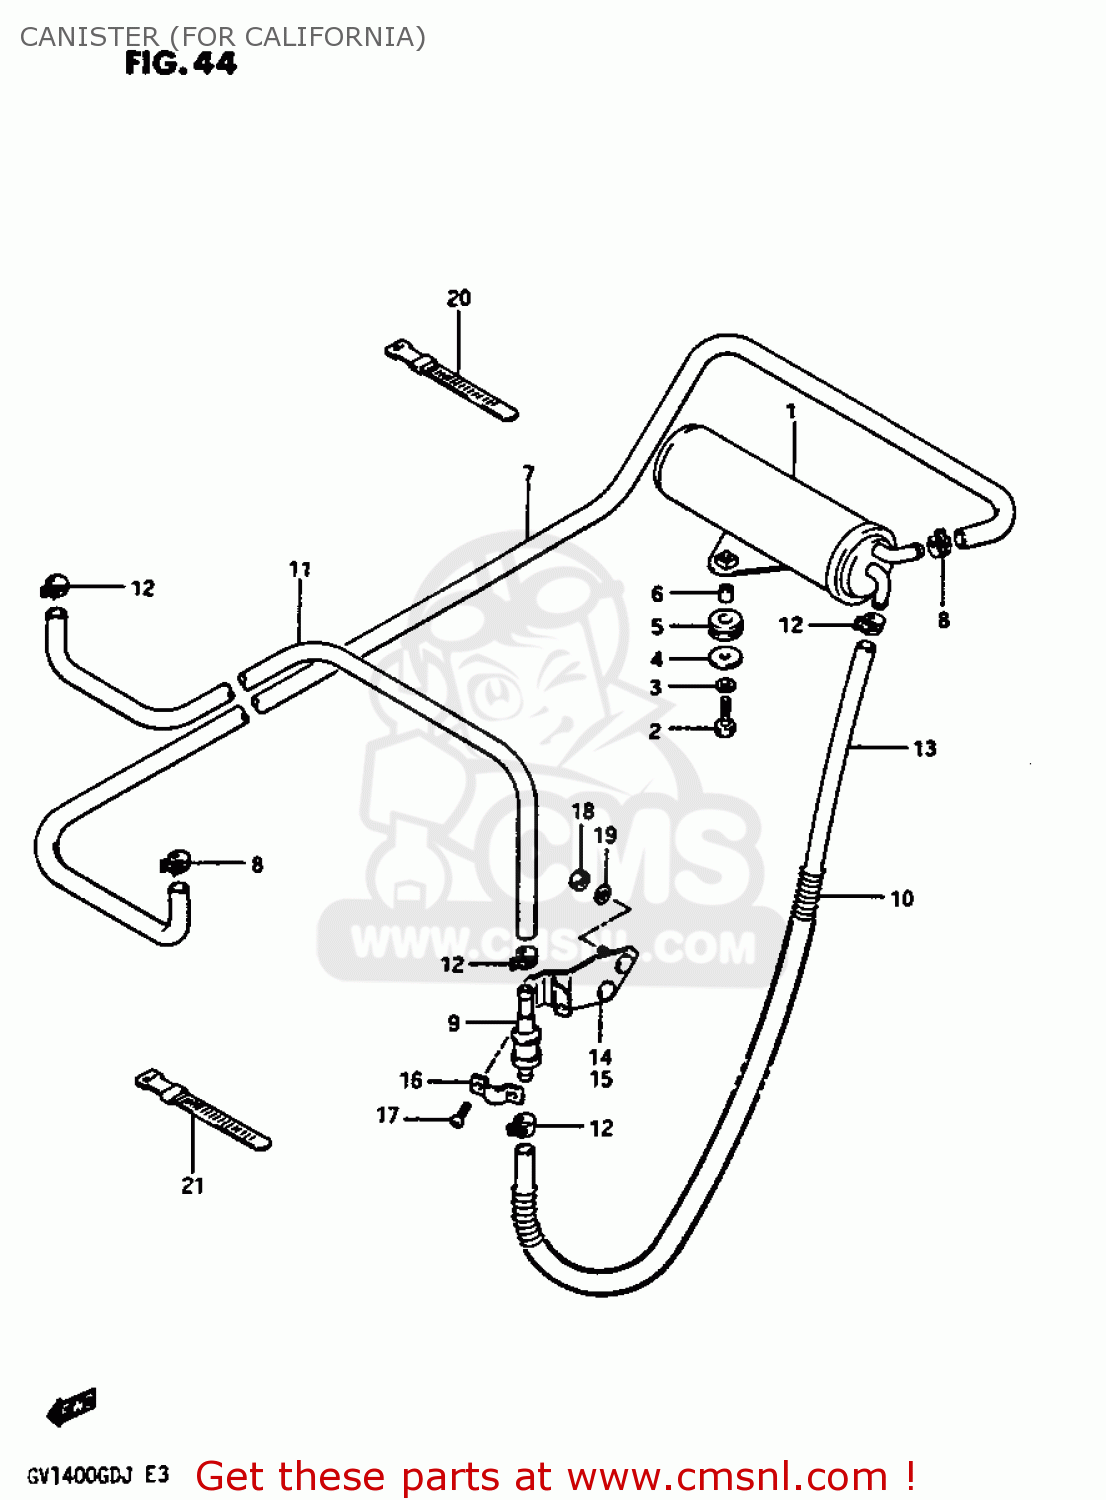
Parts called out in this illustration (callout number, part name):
1	(CA) CANISTER ASSEMBLY,CHARCOAL
2	BOLT
3	WASHER,LOCK
4	WASHER (6.5X18X1.6)
5	CUSHION
6	SPACER(6.1X9X7.5)
7	(CA) HOSE
8	CLAMP
9	VALVE,FUEL TANK BREATHER
10	SPRING
11	HOSE
12	(CA) CLIP
13	(CA) HOSE
14	PLATE,TANK BREATHER VALVE
15	CUSHION
16	PLATE,FUEL TANK BREATHER NO.2
17	SCREW
18	NUT 6MM
19	WASHER(6.5X18X1)
20	CLAMP
21	CLAMP(L:187)
